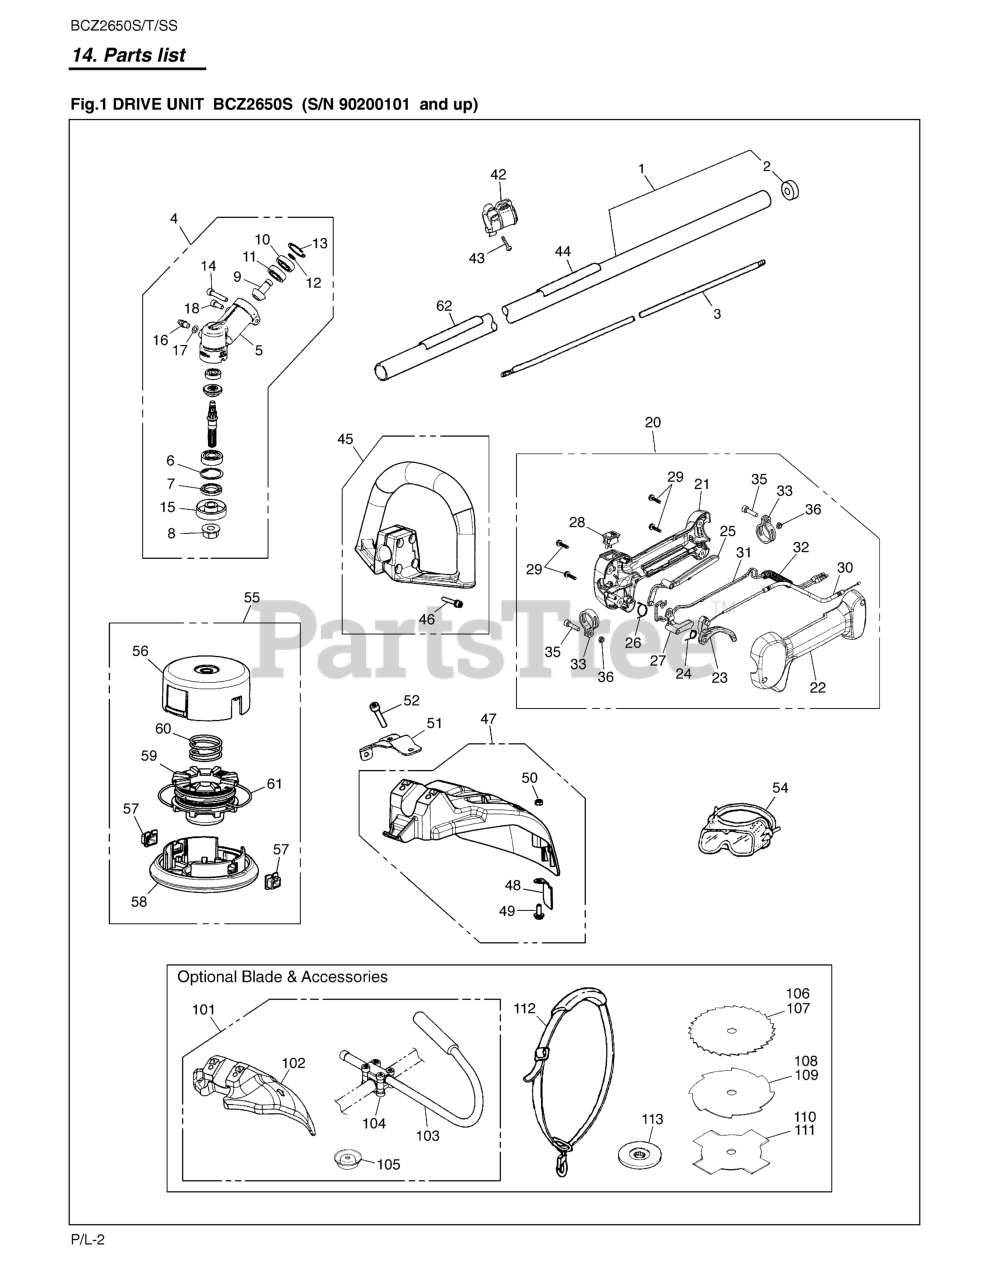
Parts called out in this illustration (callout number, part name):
1	PIPE COMP.
2	SEAL
3	SHAFT
4	GEARCASE ASSY.
5	GEARCASE
6	SNAP RING
7	SEAL
8	NUT
9	PINION
10	BEARING
11	BEARING
12	SNAP RING
13	SNAP RING
14	BOLT, TORX
15	HOLDER (A)
16	FITTING, GREASE
17	WASHER, FITTING
18	BOLT
20	GRIP ASSY
23	LEVER, THROTTLE
24	SPRING, THROTTLE
25	LEVER, SAFETY
27	LEVER, JOINT
28	SWITCH
29	SCREW
30	CABLE COMP
31	CORD COMP
32	TUBE
35	BOLT TORX
42	HANGER ASSY
43	SCREW
44	NAME PLATE
45	HANDLE ASSY
46	SCREW
47	GUARD COMP.
48	BLADE
49	SCREW
50	NUT
51	BRACKET
52	BOLT
54	GOGGLE
55	TAP HEAD COMP.
56	CASE
57	EYELET
58	COVER
59	CORD HOLDER
60	SPRING
61	CORD
62	LABEL, CAUTION
101	BLADE KIT (PRODUCT)
102	GUARD
103	HANDLE, J
104	BRACKET ASSY.
105	COVER
106	BLADE, 9
107	BLADE, 9
108	BLADE, 8
109	BLADE, 9
110	BLADE, 8
111	BLADE, 9
112	STRAP ASSY
113	HOLDER (B)
